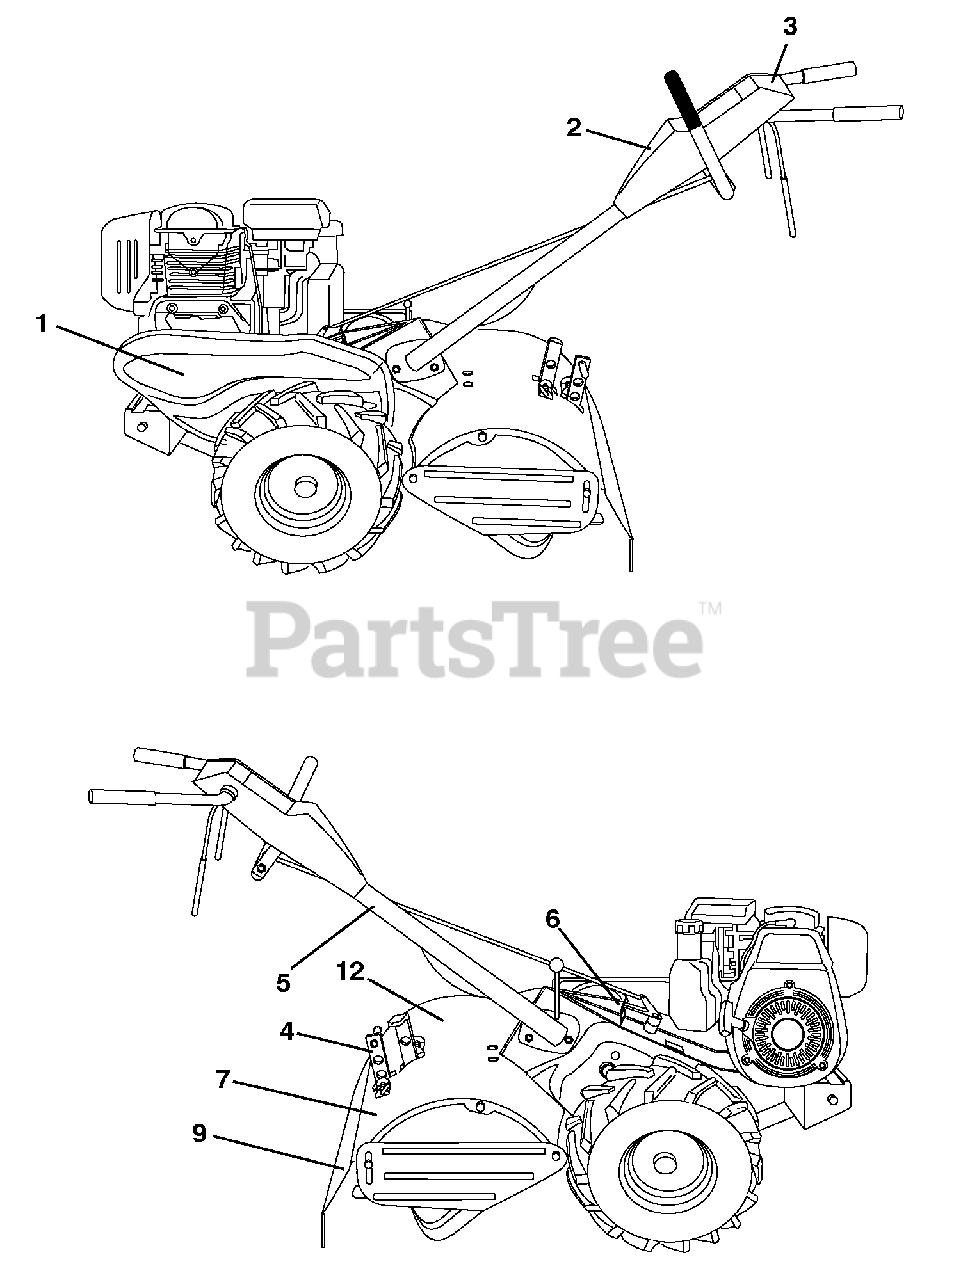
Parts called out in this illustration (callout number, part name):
1	Decal, Badge
2	Decal, Console
3	Decal, Console
4	Decal, Tine Shield
5	Decal, Hand Placement
6	Decal, Shift Indicator
7	Decal, Reverse
9	Decal, Warning, Rotating Tines
12	Decal, Forward
